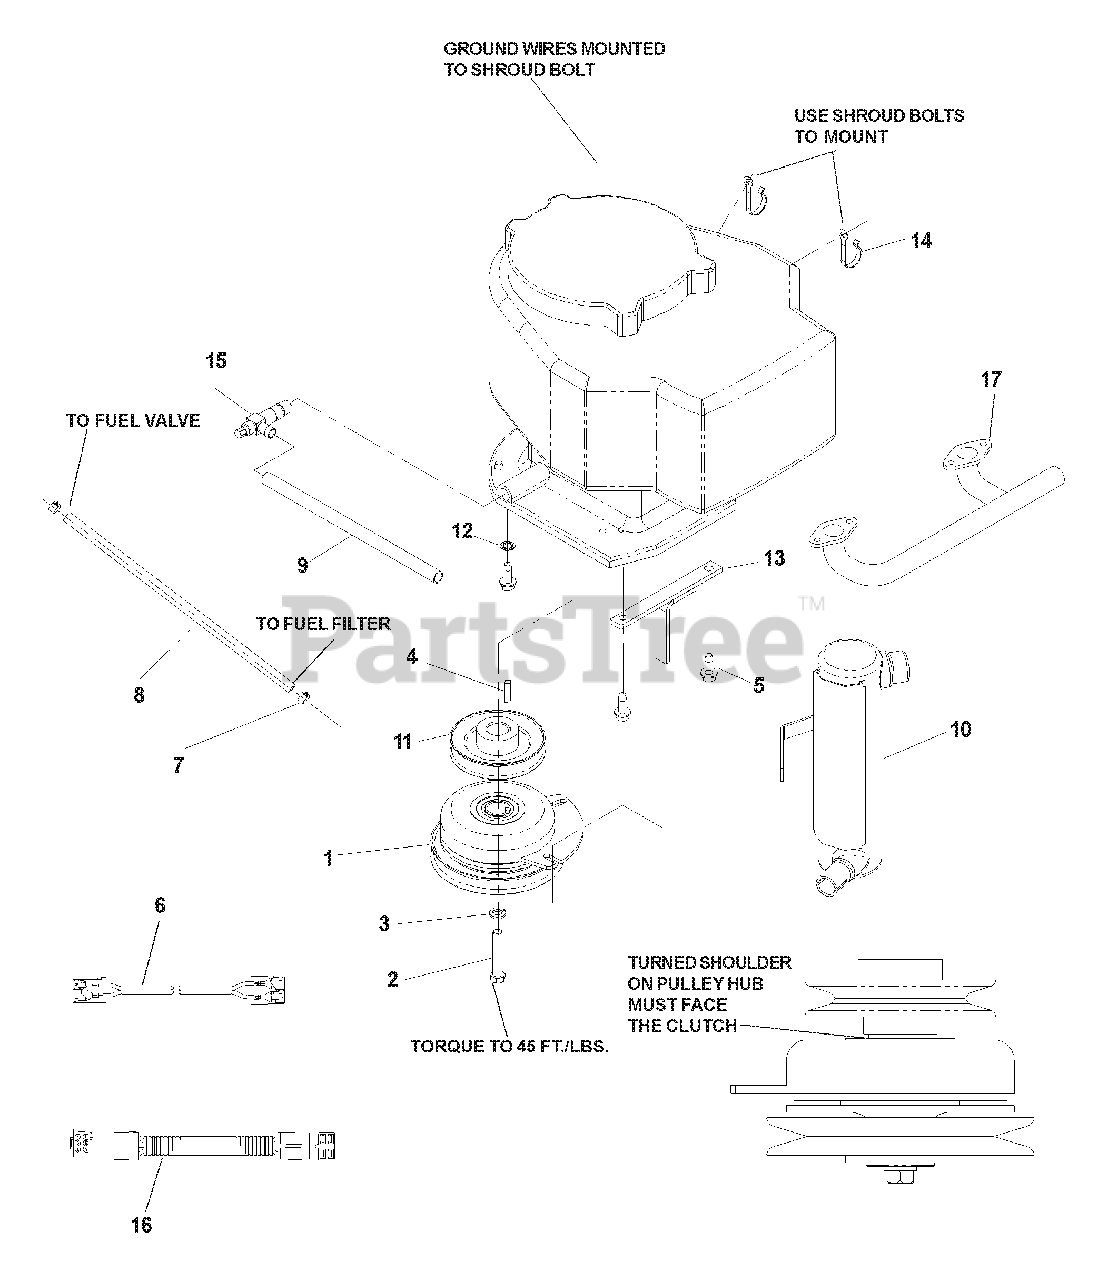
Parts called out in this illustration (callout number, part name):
1	CLUTCH, 125 FT/LB
2	HCS 7/16-20 X 2 1/2, GR5
3	LOCKWASHER, 7/16
4	KEY, 1/4" SQ. X 1 1/8"
5	BOLT, 3/8-16 X 1, THREAD FORMING
6	CLUTCH HARNESS
7	HOSE CLAMP
8	FUEL LINE, 24"
9	HOSE, OIL DRAIN
12	WASHER, 3/8, INTERNAL TOOTH
13	CLUTCH TIE DOWN WELDMENT
15	DRAIN VALVE
